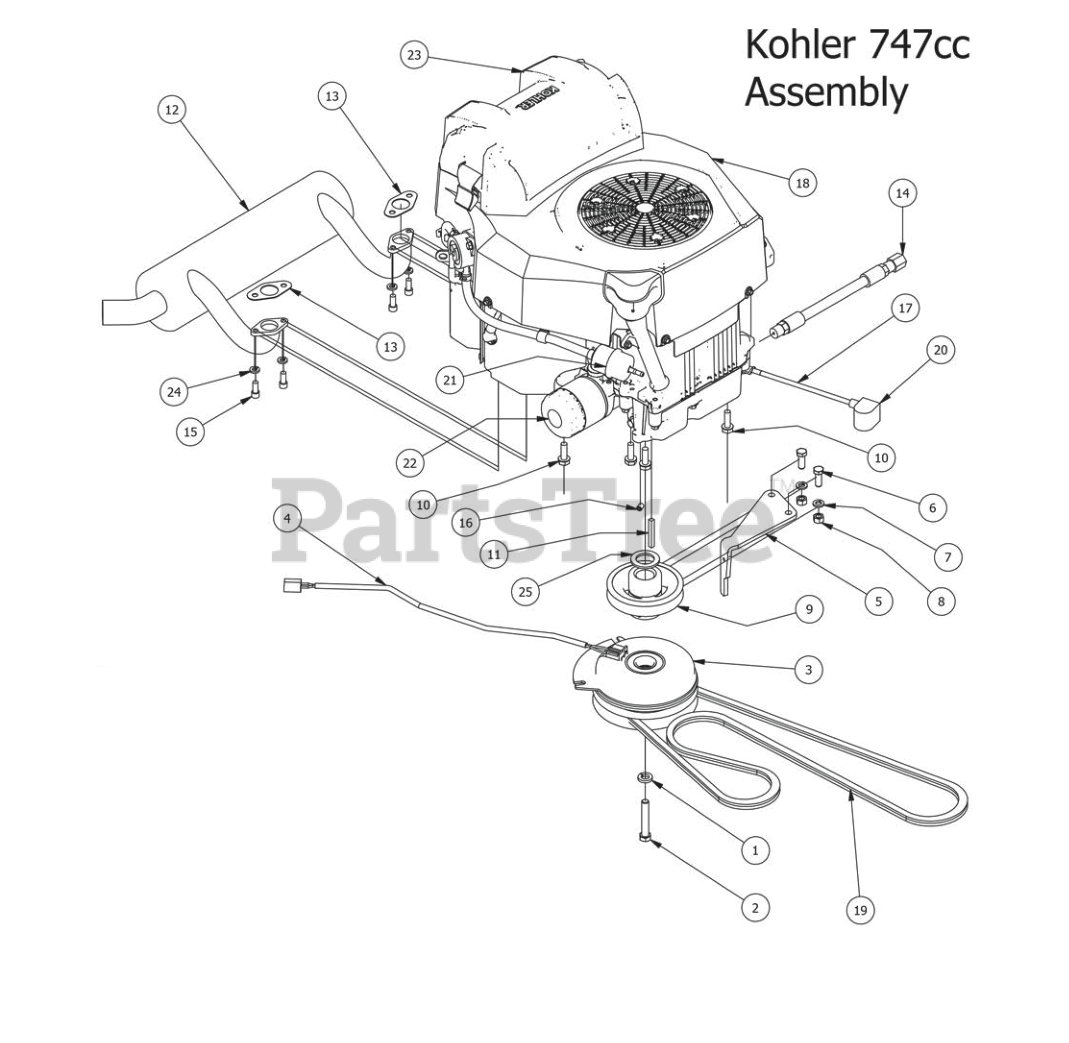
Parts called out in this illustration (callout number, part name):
1	7/16" Lock Washer
2	7/16" x 2 1/2" Hex Bolt
3	Clutch Assembly
4	Clutch Pigtail
5	PTO Engager Holder
6	3/8" x 1" Hex Bolt
7	3/8" Lock Washer
8	3/8" Hex Nut
9	4 3/4 Motor Pulley
10	3/8 x 1 1/8 bolt
11	1/4 x 2 Square key Stock
12	2014 Kohler Outlaw Muffler
13	Exhaust Gasket
14	Oil drain Valve
15	5/16-18 x 3/4 Socket C/S
16	5/16 Set Screw
17	Starter to chassis cable
18	Kohler-2014 CZT/Outlaw 747cc
20	Black Boot For ground cable.
21	725 & 747 Kohler Fuel Filter
22	725 & 747 Kohler Oil Filter
23	747 Kohler Air Filter CZT/Outlaw
24	5/16" Lock Washer
25	1 1/8" Flat Spacer
